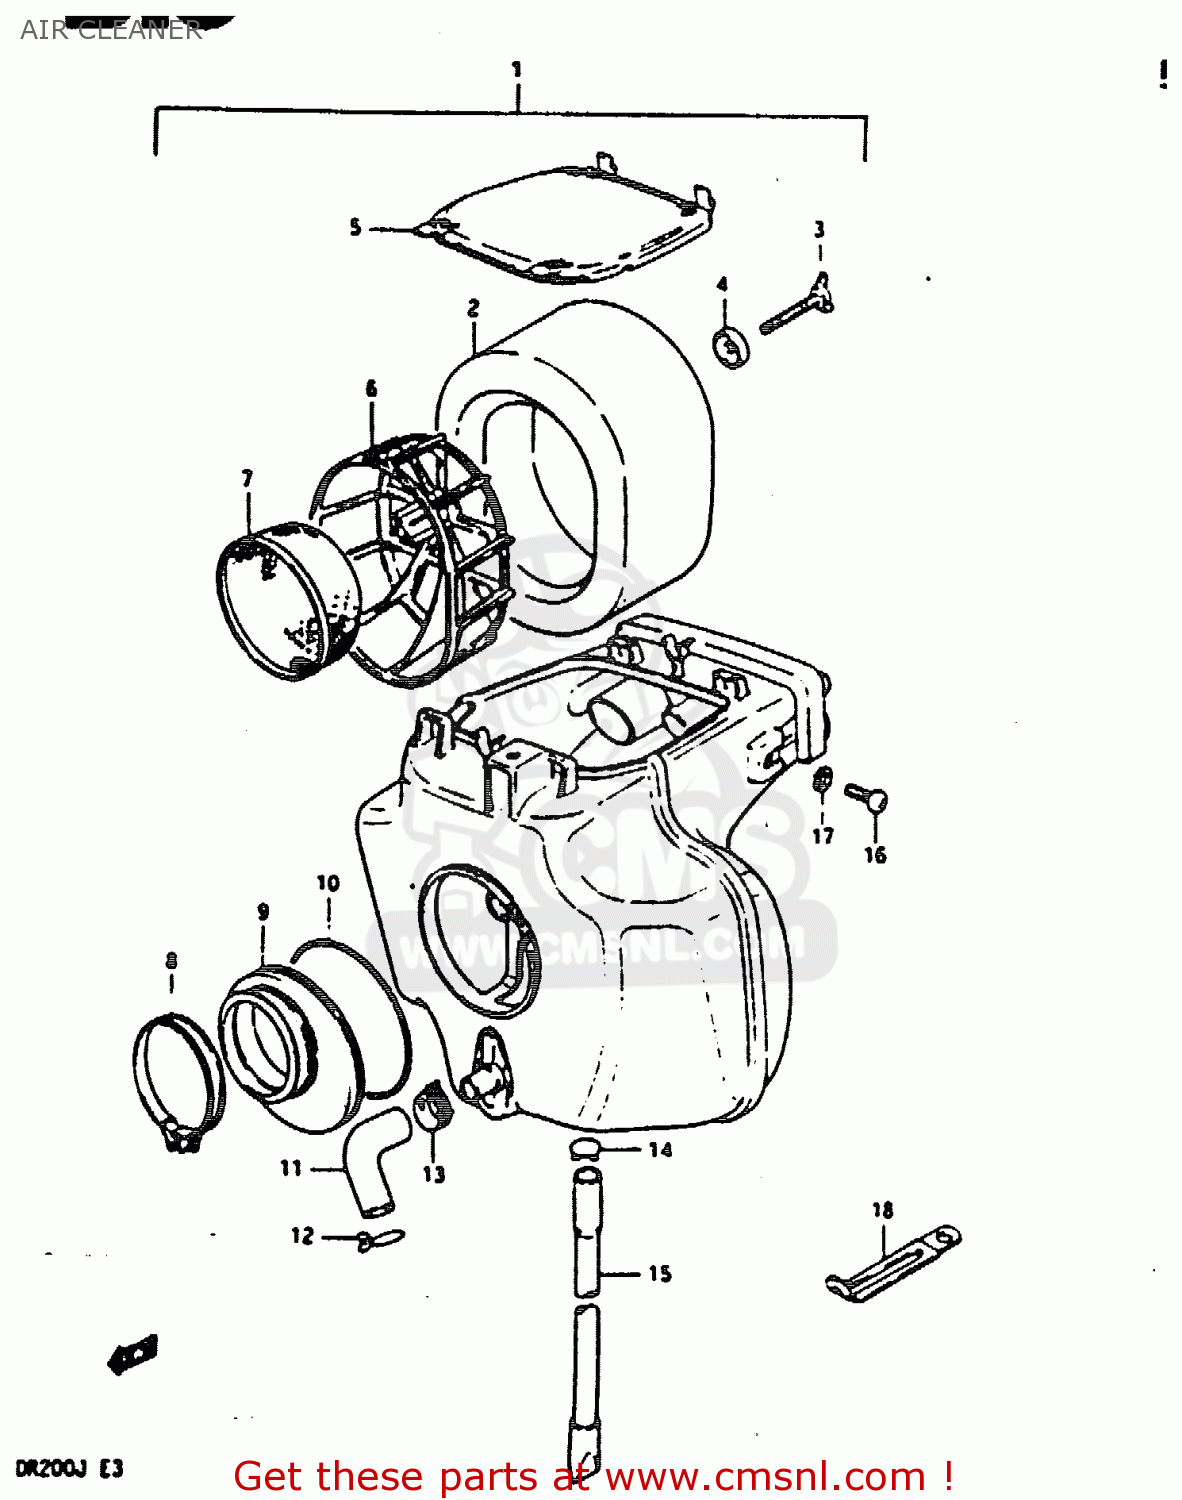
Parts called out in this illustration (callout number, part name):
1	CLEANER ASSEMBLY,AIR
2	FILTER,AIR CLEANER
3	BOLT,WING
4	WASHER,FILTER HOLDER
5	CAP
6	HOLDER,FILTER
7	TRAP
8	CLAMP
9	TUBE,AIR CLEANER OUTLET
10	CLAMP,AIR CLEANER SIDE
11	TUBE,BREATHER
12	CLIP,BREATHER TUBE
13	CLIP
14	CLIP
15	DRAIN TUBE
16	SCREW
17	WASHER,LOCK
18	CLAMP
